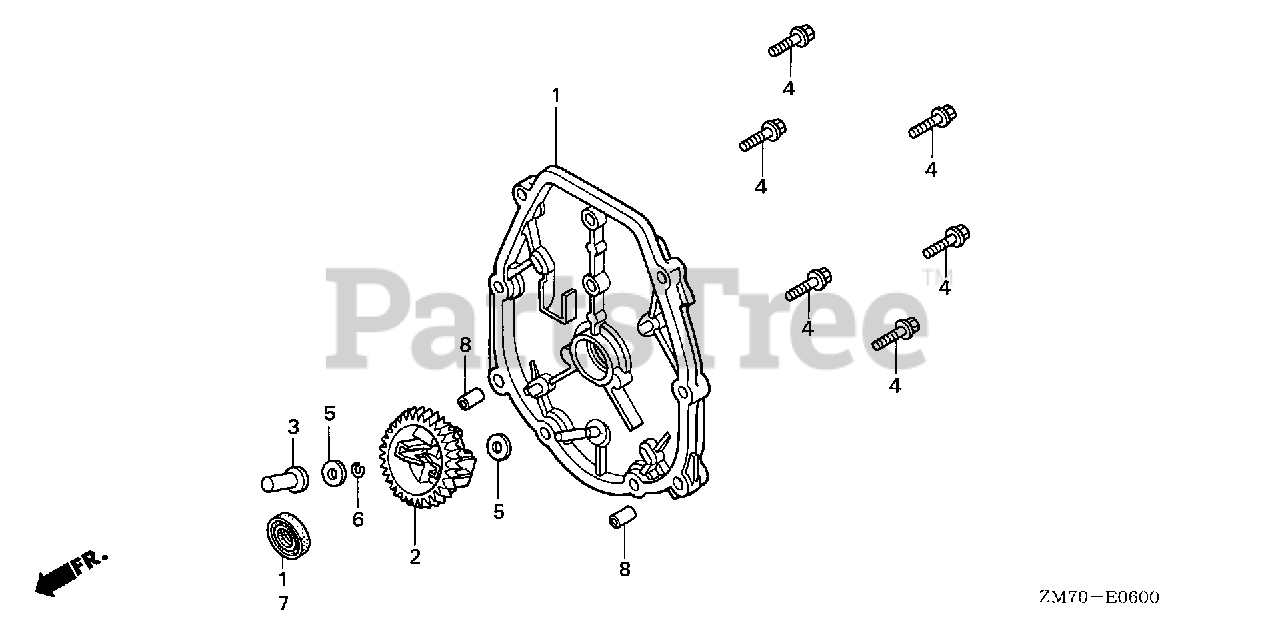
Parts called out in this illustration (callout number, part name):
1	COVER, CRANKCASE SIDE
2	GOVERNOR ASSY.
3	SLIDER, GOVERNOR
4	BOLT, FLANGE (5X23)
5	WASHER (4.2X13)
6	CLIP, GOVERNOR HOLDER
7	OIL SEAL (17X27X5) (KOYO)
8	PIN, DOWEL (6X10)
